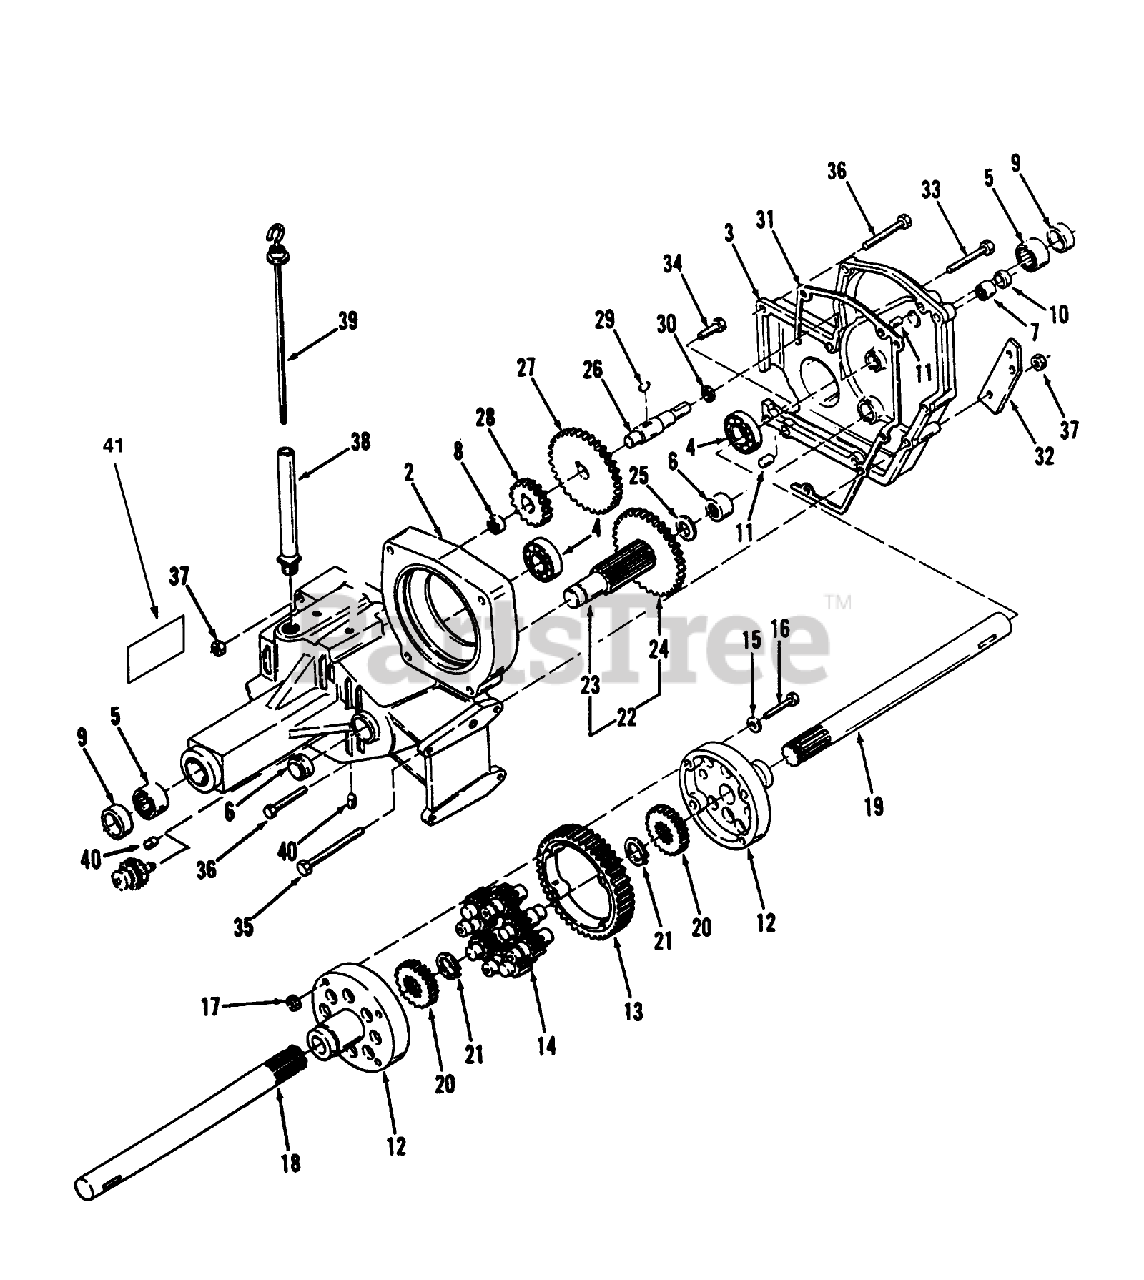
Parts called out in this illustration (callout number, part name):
2	CASE-TRANSMISSION RH
4	BEARING-BALL
5	BEARING
6	BEARING-NEEDLE
7	NEEDLE BEARING
8	BEARING-NEEDLE
9	SEAL-OIL
11	PIN-LOCATING
12	END CAP-DIFFERENTIAL
13	GEAR-DIFFERENTIAL RING, 43T
14	GEAR-PINION, 11T
15	WASHER
17	NUT-HEX
20	GEAR-AXLE DIFFERENTIAL
21	RING-SNAP
23	PINION SHAFT
25	WASHER-THRUST
26	SHAFT GEAR
27	GEAR 46 TEETH
29	WOODRUFF KEY
31	GASKET-TRANSMISSION
33	SCREW-HH
34	SCREW-HH
35	SCREW-HH
36	SCREW-HH
37	NUT-LOCK, NI
38	NIPPLE-TRANS FILL
41	DECAL - DANGER
